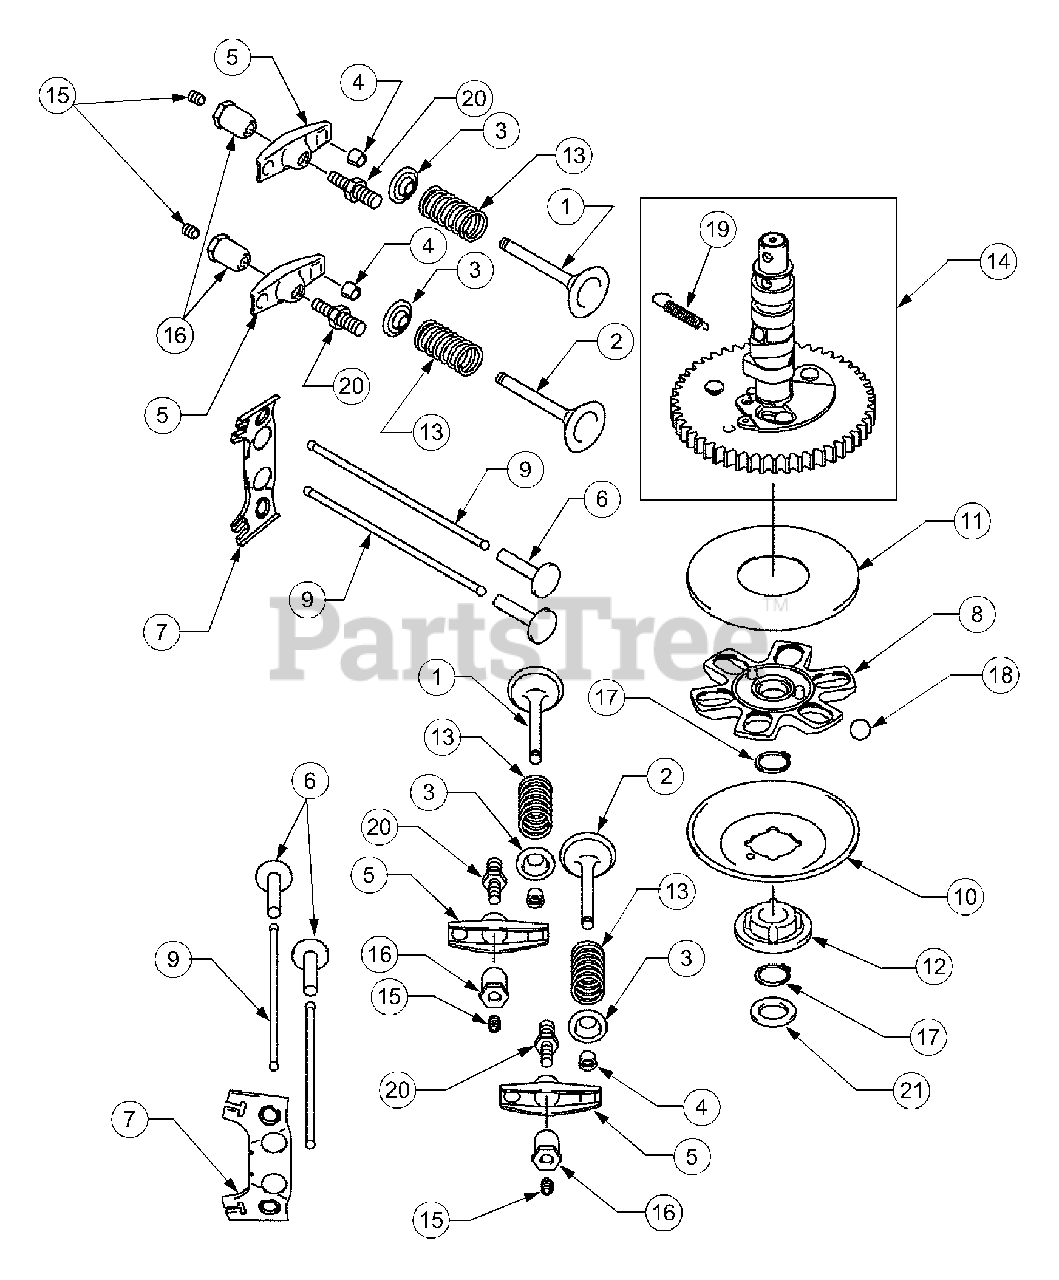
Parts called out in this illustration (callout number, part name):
1	Valve, Intake
2	Valve, Exhaust
3	Retainer, Valve Spring
5	Arm, Rocker
10	Plate
12	Sleeve
13	Spring, Engine Valve
14	Camshaft, Comp
17	Ring, Snap
18	Ball
19	Spring
20	Bolt
